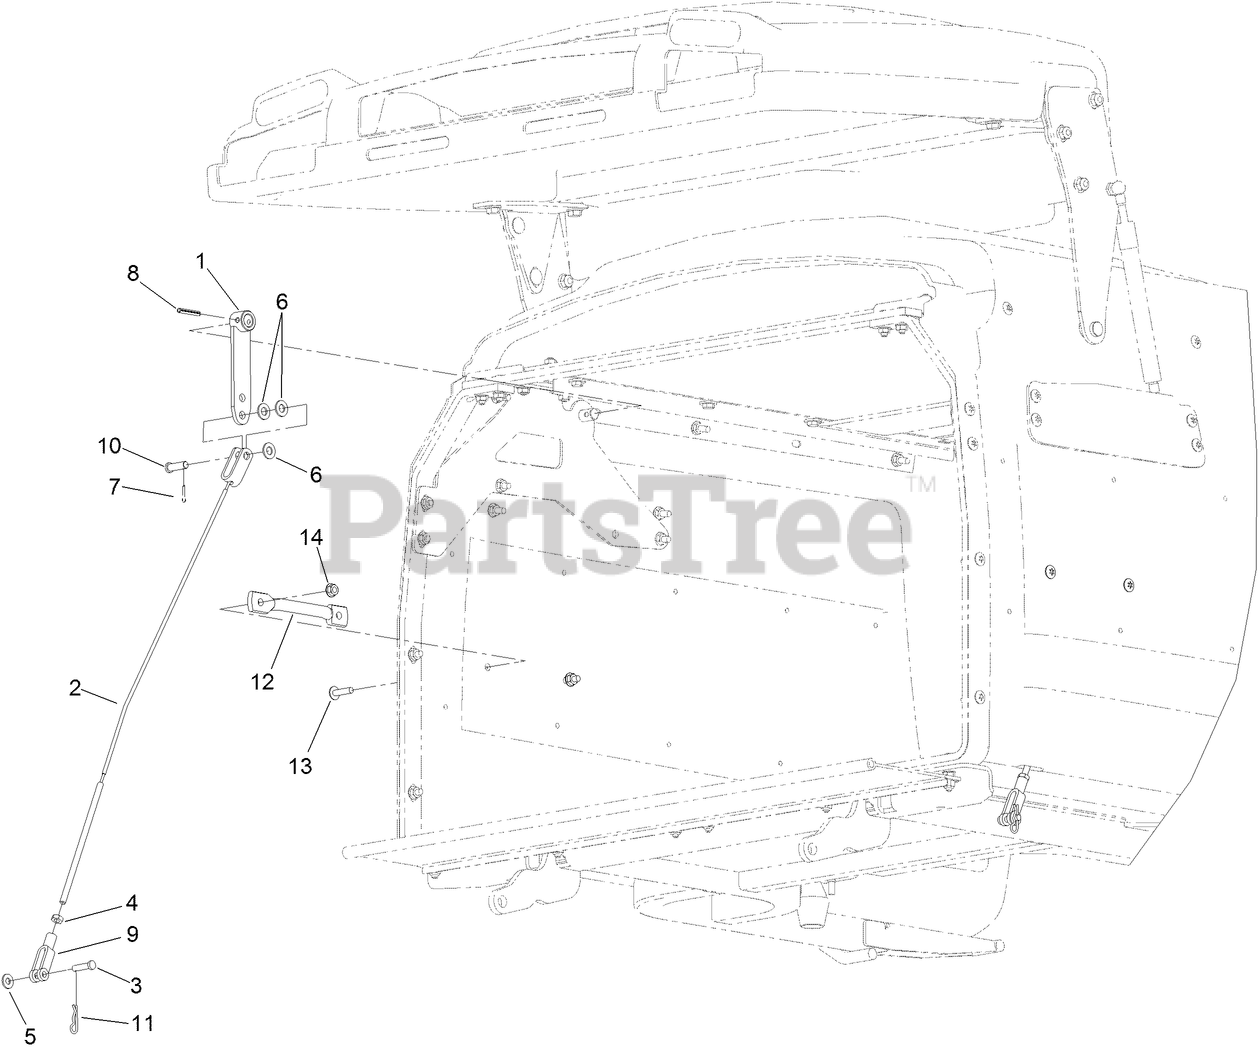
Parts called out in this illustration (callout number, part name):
1	ARM-DOOR
2	CABLE ASM
4	NUT-JAM
5	WASHER-FLAT
6	WASHER-PLAIN
7	PIN-COTTER
8	PIN-ROLL, SLOTTED
10	PIN-CLEVIS
11	PIN-COTTER
12	GUIDE-CABLE
13	SCREW-TTH
14	NUT-HF
